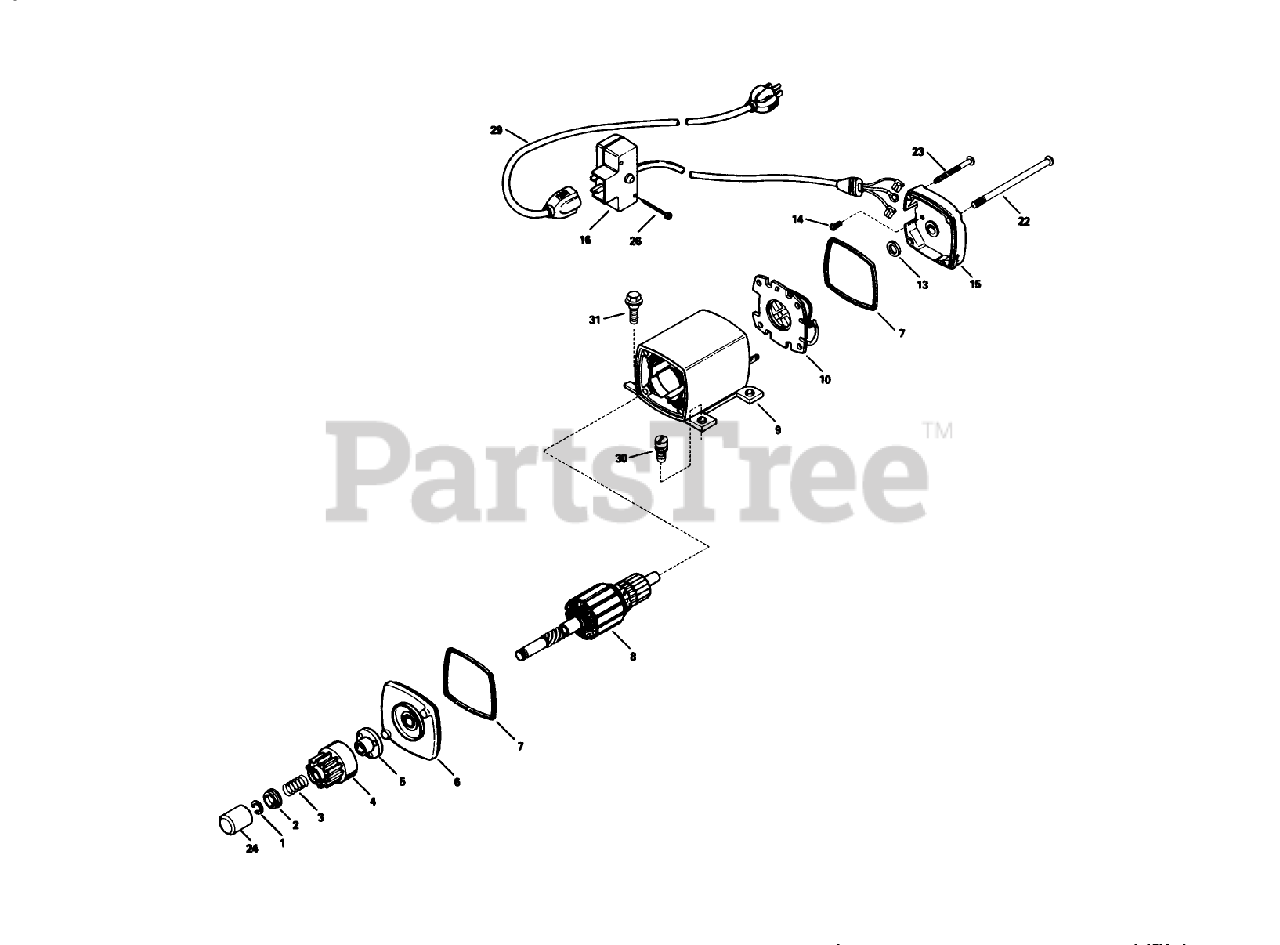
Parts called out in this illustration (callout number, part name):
1	Ring-Retainer
2	Retainer-Spring
3	Spring-Anti Drift
4	Gear
5	Nut-Engaging
6	Cap Assembly-Cap End (Incl. Ref. #7)
7	O-Ring
8	Armature
9	Housing Assy.
10	Card ASM
13	Washer-Thrust
14	Screw-Ground
15	Cap Assembly (Incl. Ref. #7)
16	Box Assembly-Switch (Incl. Ref. #26)
22	Bolt-Case
23	Screw-Ground
24	Cover-Dust
26	Screw
29	Cord-Extension
30	Screw
31	Screw (1/4-20x1/2)
